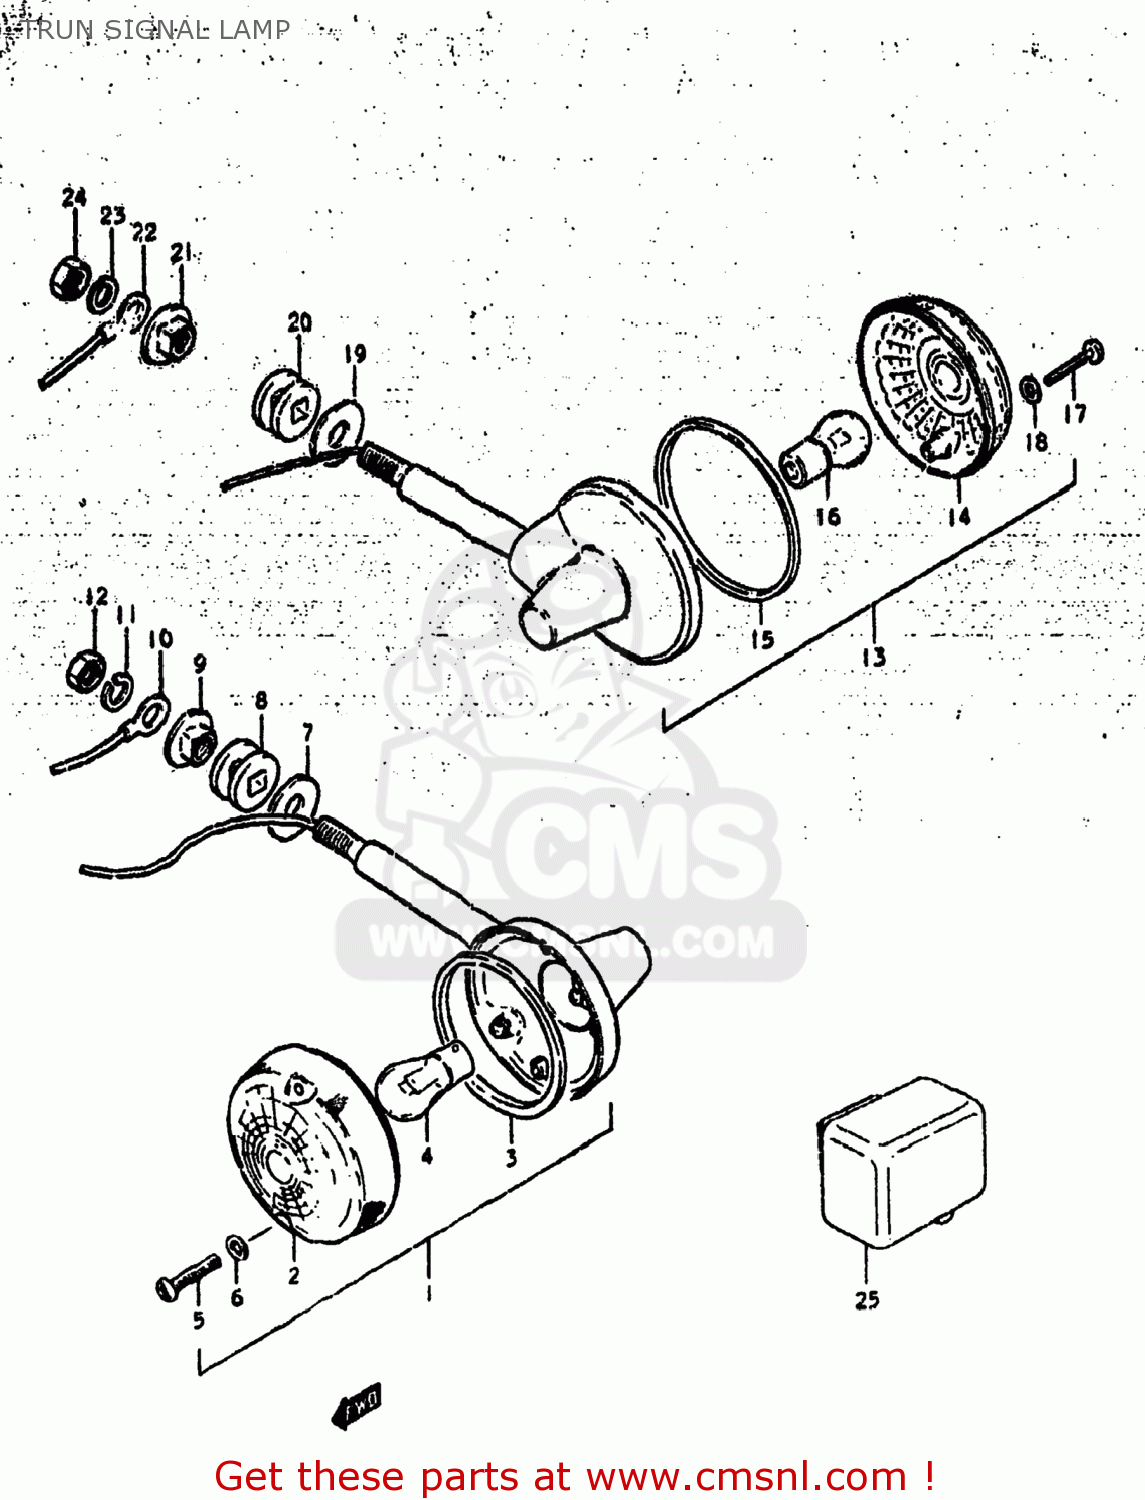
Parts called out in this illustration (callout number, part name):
1	LAMP ASSEMBLY,FRONT TURN SIGNAL
2	LENS
3	GASKET (NAS)
4	BULB(12V23W,STANLEY,A4577A)
5	SCREW
6	GASKET (NAS)
7	WASHER
8	CUSHION
9	SPACER,RR TURNSIGNAL LAMP
10	WIRE
11	LOCK WASHER
12	NUT
13	LAMP ASSEMBLY,REAR TURN SIGNAL
14	LENS
15	GASKET (NAS)
16	BULB(12V23W,STANLEY,A4577A)
17	SCREW
18	GASKET (NAS)
19	WASHER
20	CUSHION
21	SPACER,RR TURNSIGNAL LAMP
22	LEAD WIRE,EARTH
23	LOCK WASHER
24	NUT
25	RELAY,TURN SIGNAL
